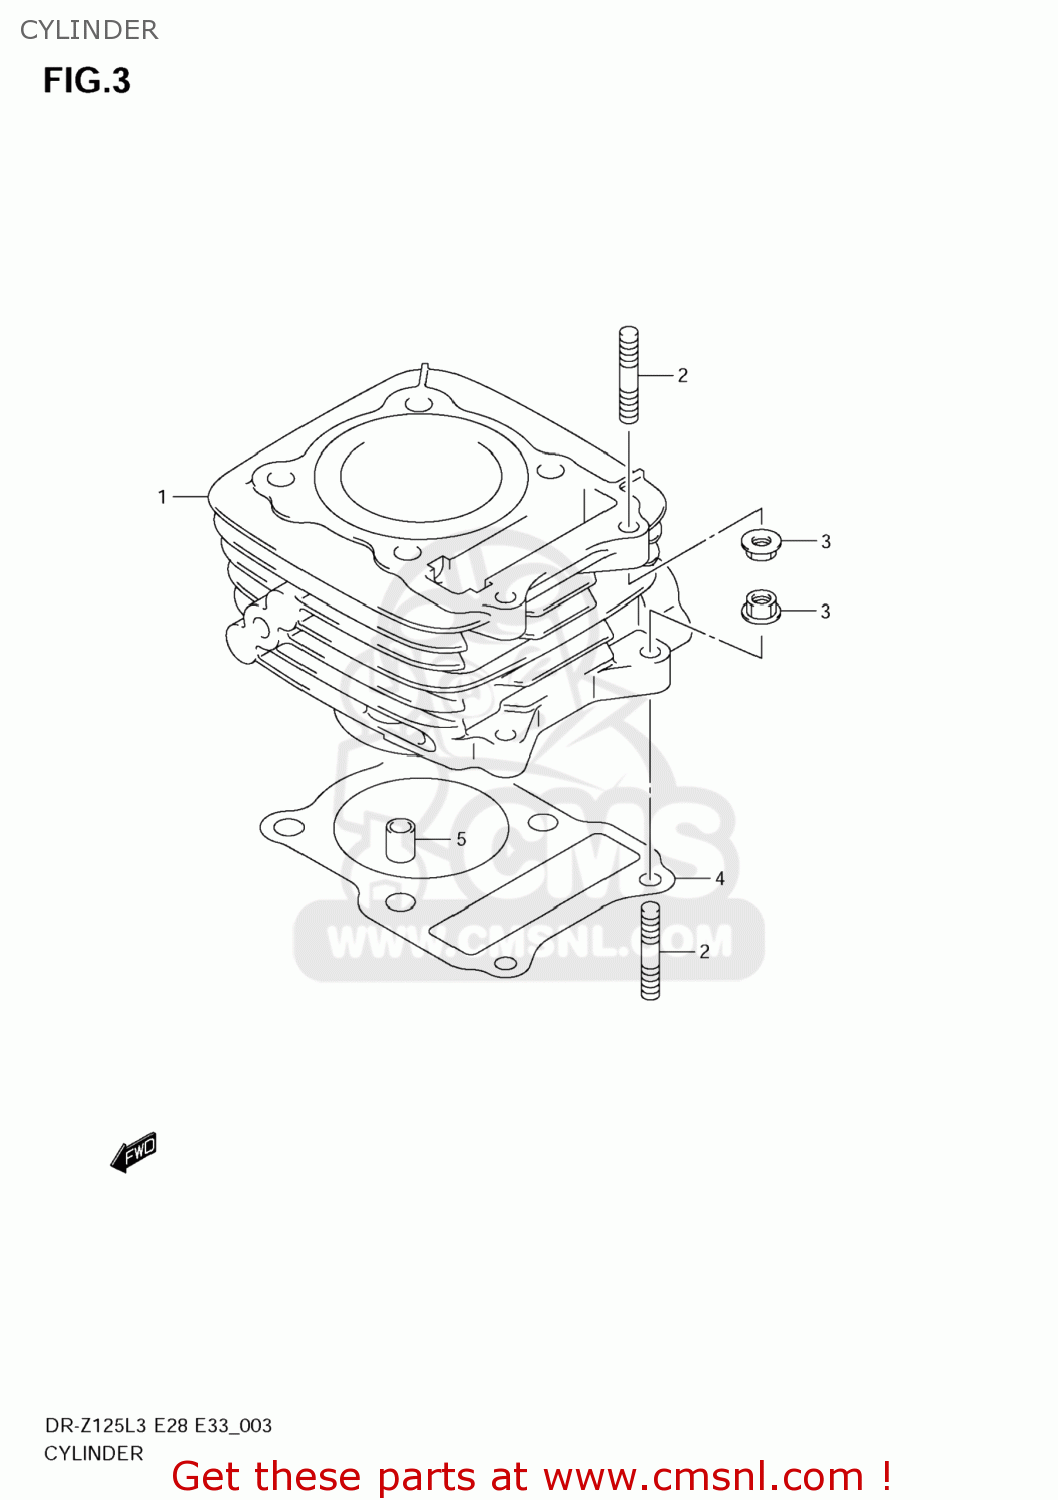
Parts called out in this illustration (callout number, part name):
1	CYLINDER
2	BOLT,STUD
3	NUT
4	GASKET,CYLINDER (NAS)
5	PIN
